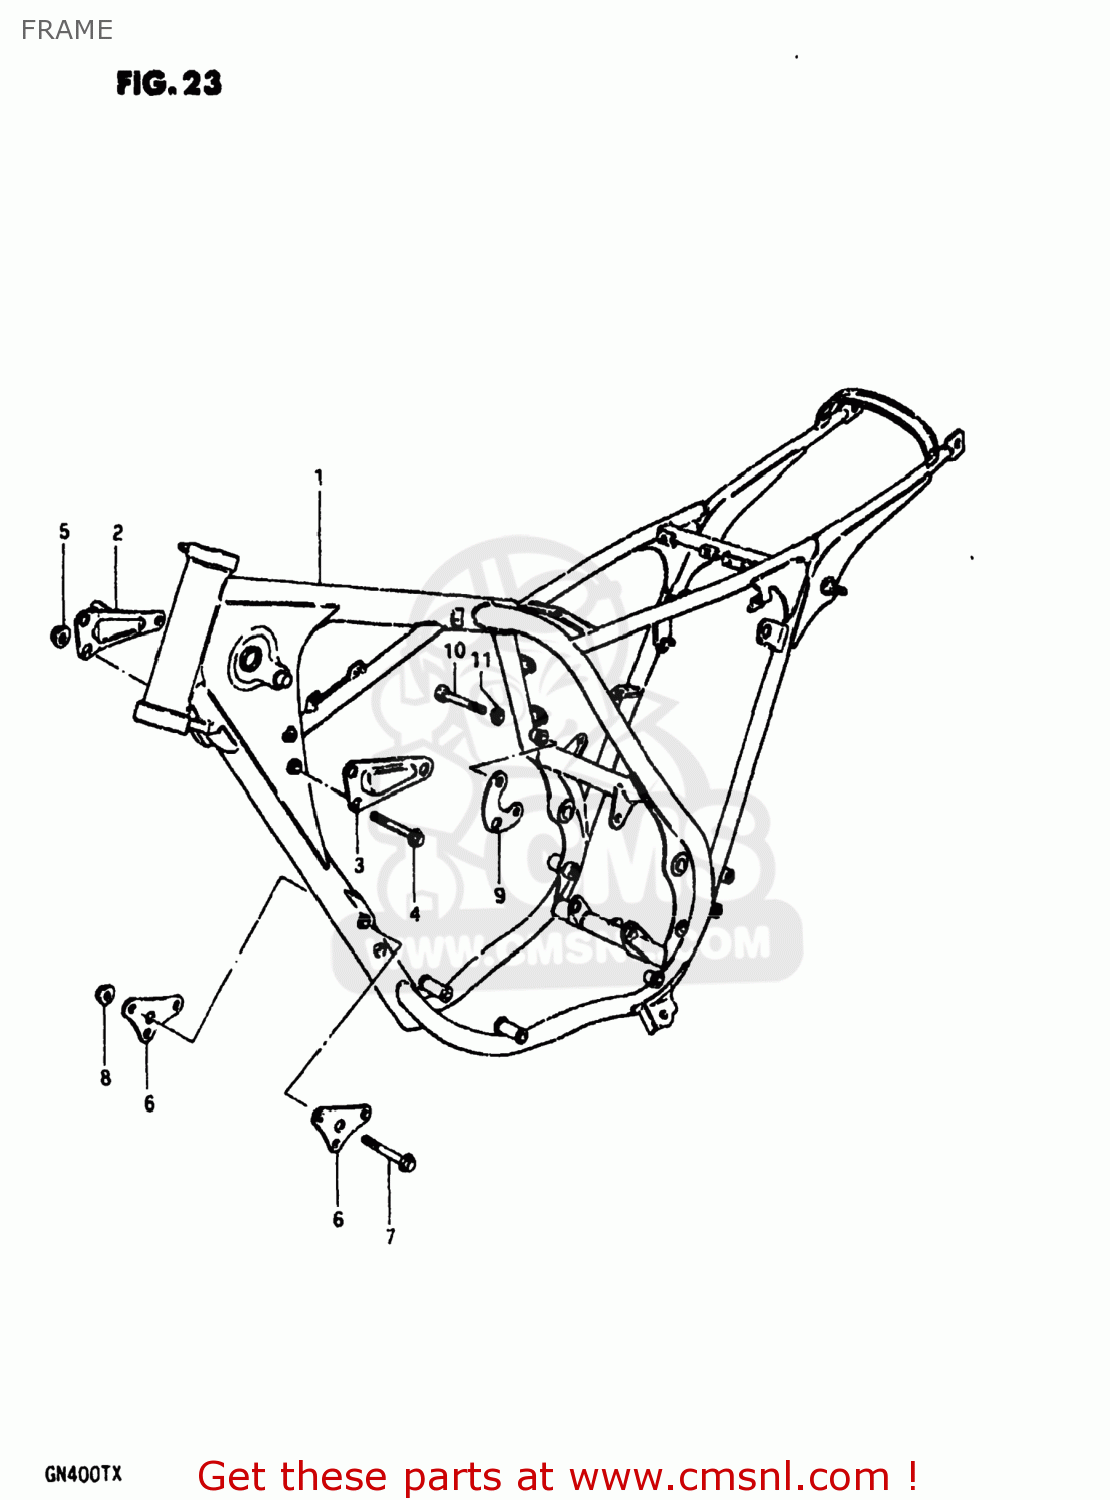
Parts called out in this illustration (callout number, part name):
1	FRAME
2	PLATE,ENGINE MOUNTING,UPPER
3	PLATE,ENGINE MOUNTING
4	BOLT (6X70)
5	NUT
6	PLATE,ENGINE MOUNTING
7	BOLT (8X70)
8	NUT
9	PLATE,ENGINE MOUNTING
10	BOLT 8X55
11	LOCK WASHER
